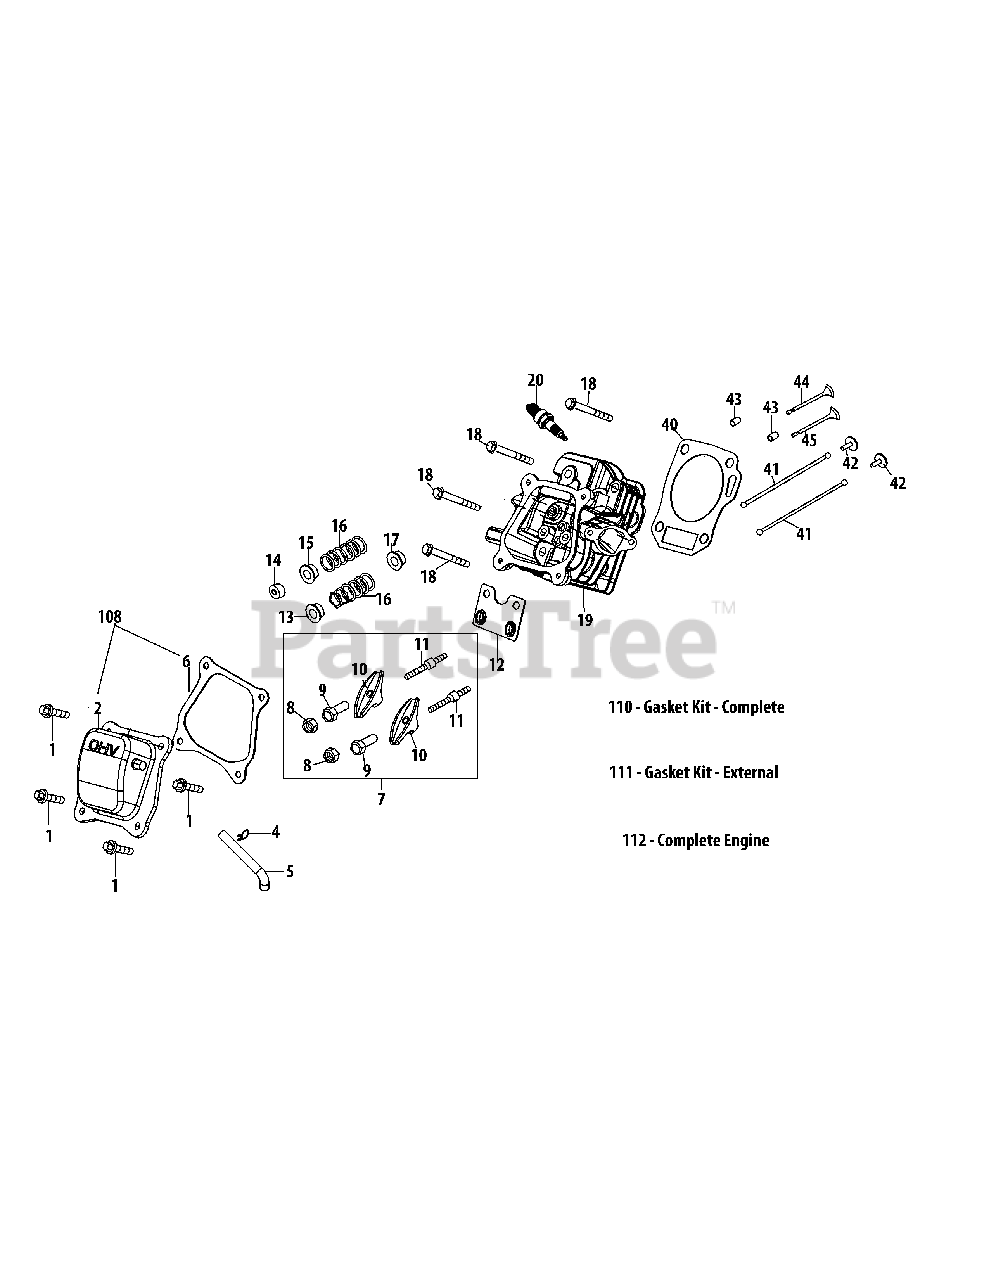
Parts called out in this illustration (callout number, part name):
1	Bolt:M,6X16
2	Valve Cover
4	Breather Hose Clamp
5	Breather Hose
6	Valve Cover Gasket
7	Rocker Arm Assembly
8	Pivot Locking Nut
10	Rocker Arm
11	Pivot Bolt
12	Push Rod Guide
13	Valve Spring Retainer
14	Exhaust Valve Adjuster
15	Exhaust Valve Spring Retainer
16	Valve Spring
17	Intake Valve Seal
18	Bolt:M8X55 Zinc Coated
19	Cylinder Head Assembly
20	Spark Plug
40	Cylinder Head Gasket
41	Push Rod Kit
42	Tappet
43	Dowel Pin 10X16
44	Valve Kit
45	Valve Kit
108	Valve Cover Kit
110	Gasket Kit - Complete
111	Gasket Kit - External
112	Complete Engine
